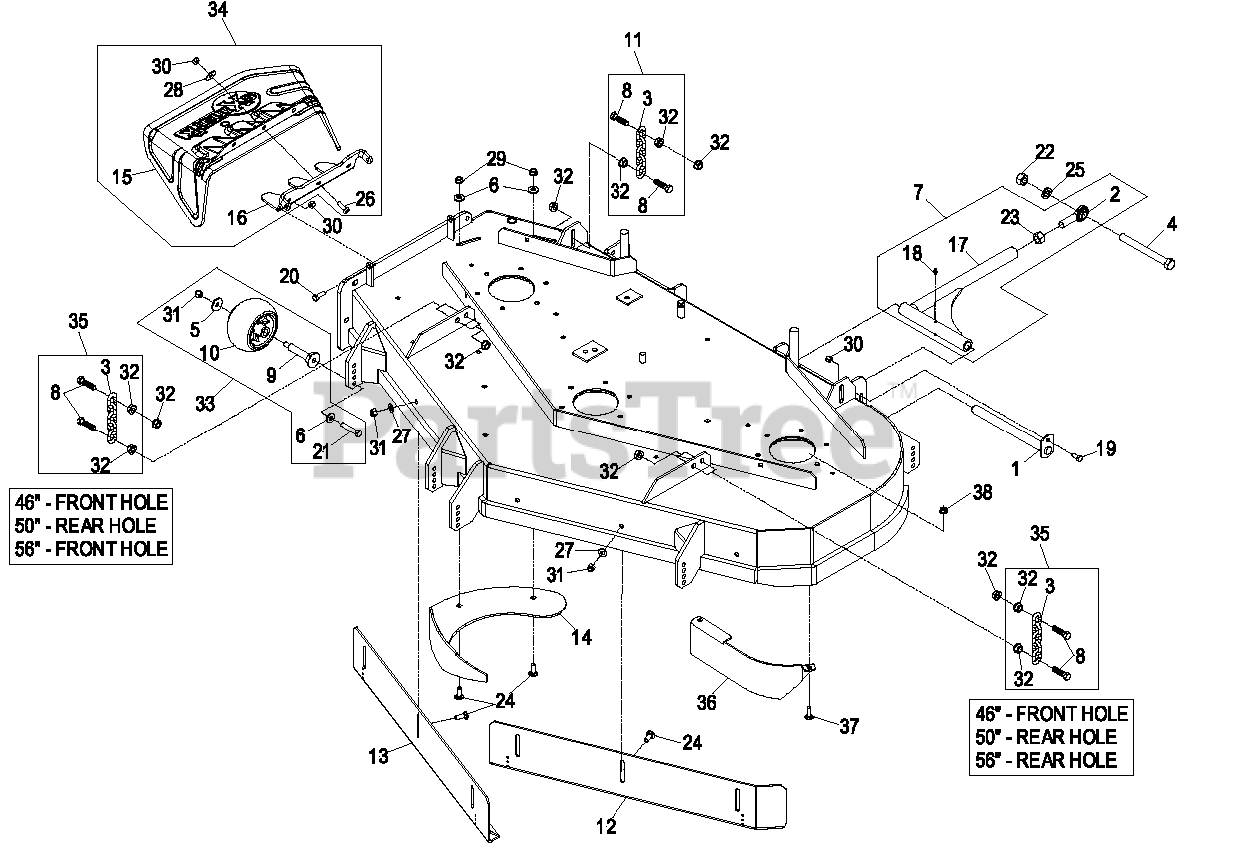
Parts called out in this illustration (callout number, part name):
1	PIN-STRUT
2	BALLJOINT-SPHERICAL
3	CHAIN-LIFT, DECK
6	WASHER-BELLEVILLE
7	STRUT ASM
8	SCREW-HH
10	ROLLER-SCALP, ANTI
11	DECK CHAIN ASM
12	WLD,BAFFLE FRT LH 505
13	WLD,BAFFLE FRT RH 505
14	WLD,DOGLEG 465
14	WLD,DOGLEG 505
14	WLD,DOGLEG 565
15	CHUTE,DISCHARGE
16	BRACKET,DISCHARGE CHUTE
18	FITTING-GREASE
19	SCREW-HH
20	SCREW-HH
21	SCREW-HH
22	NUT-HEX
23	NUT-HEX
24	SCREW-CARR
25	WASHER-LOCK
26	SCREW-CARR
27	WASHER-FLAT
28	WASHER-FLAT
29	NUT-HHF, WHIZ
30	NUT-LOCK, NI
31	NUT-LOCK, NI
35	DECK CHAIN ASM
36	BAFFLE,SCROLL 465/505
36	BAFFLE,SCROLL 565
37	SCREW-CARR
38	NUT-HF, NI
